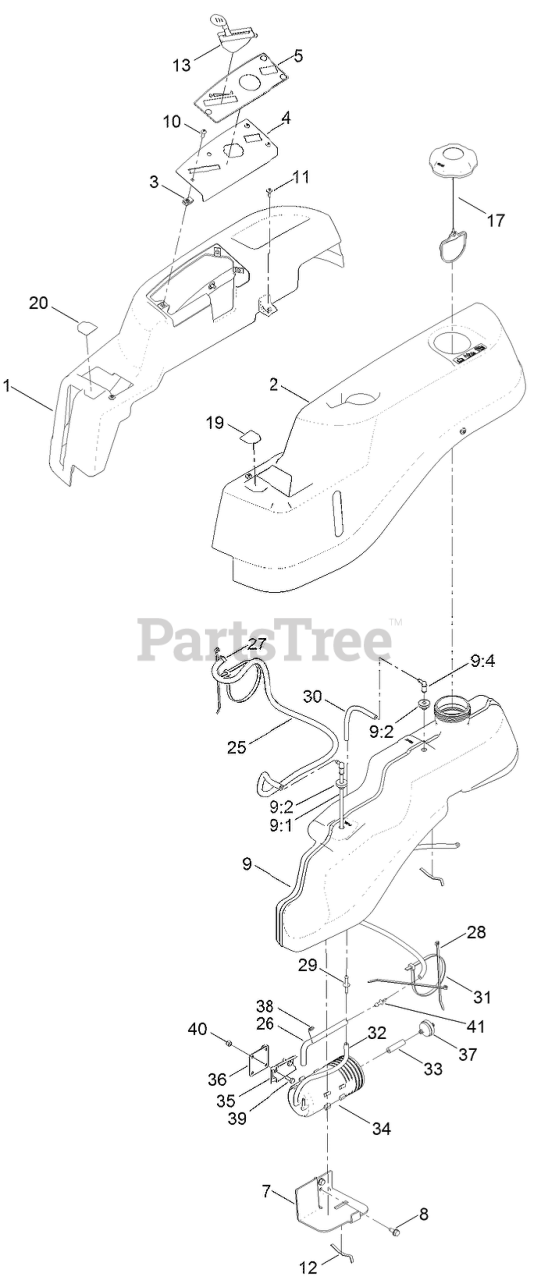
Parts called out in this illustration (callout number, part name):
1	POD-RH
2	POD-LH
4	PLATE-CONTROL
5	DECAL-PANEL, CONTROL
7	SUPPORT-TANK, FRONT
8	SCREW-HWHTF
9	FUEL TANK ASM
9:1	CONNECTOR-ELBOW, 90 DEG
9:2	BUSHING
9:4	FITTING-PLASTIC
10	SCREW-PRH
11	SCREW-SHOULDER
12	SPRING
13	CABLE-THROTTLE AND CHOKE
17	CAP-FUEL, RATCHETING
19	DECAL-CONTROL LEVER, LH
20	DECAL-CONTROL LEVER, RH
25	HOSE-FUEL
26	HOSE-FUEL
27	CLAMP-HOSE
28	TIE-CABLE
29	ADAPTOR-ORIFICE
30	HOSE-FUEL
31	TIE-CABLE
32	HOSE-FUEL
33	HOSE-FUEL
34	CANISTER-CARBON, 800CC
35	BRACKET-CANISTER, CARBON
36	PLATE-ADAPTER
37	FILTER-FUEL, INLINE
38	CARTRIDGE-VALVE, CHECK
39	SCREW-HH
40	NUT-LOCK, NI
41	FITTING-STRAIGHT
